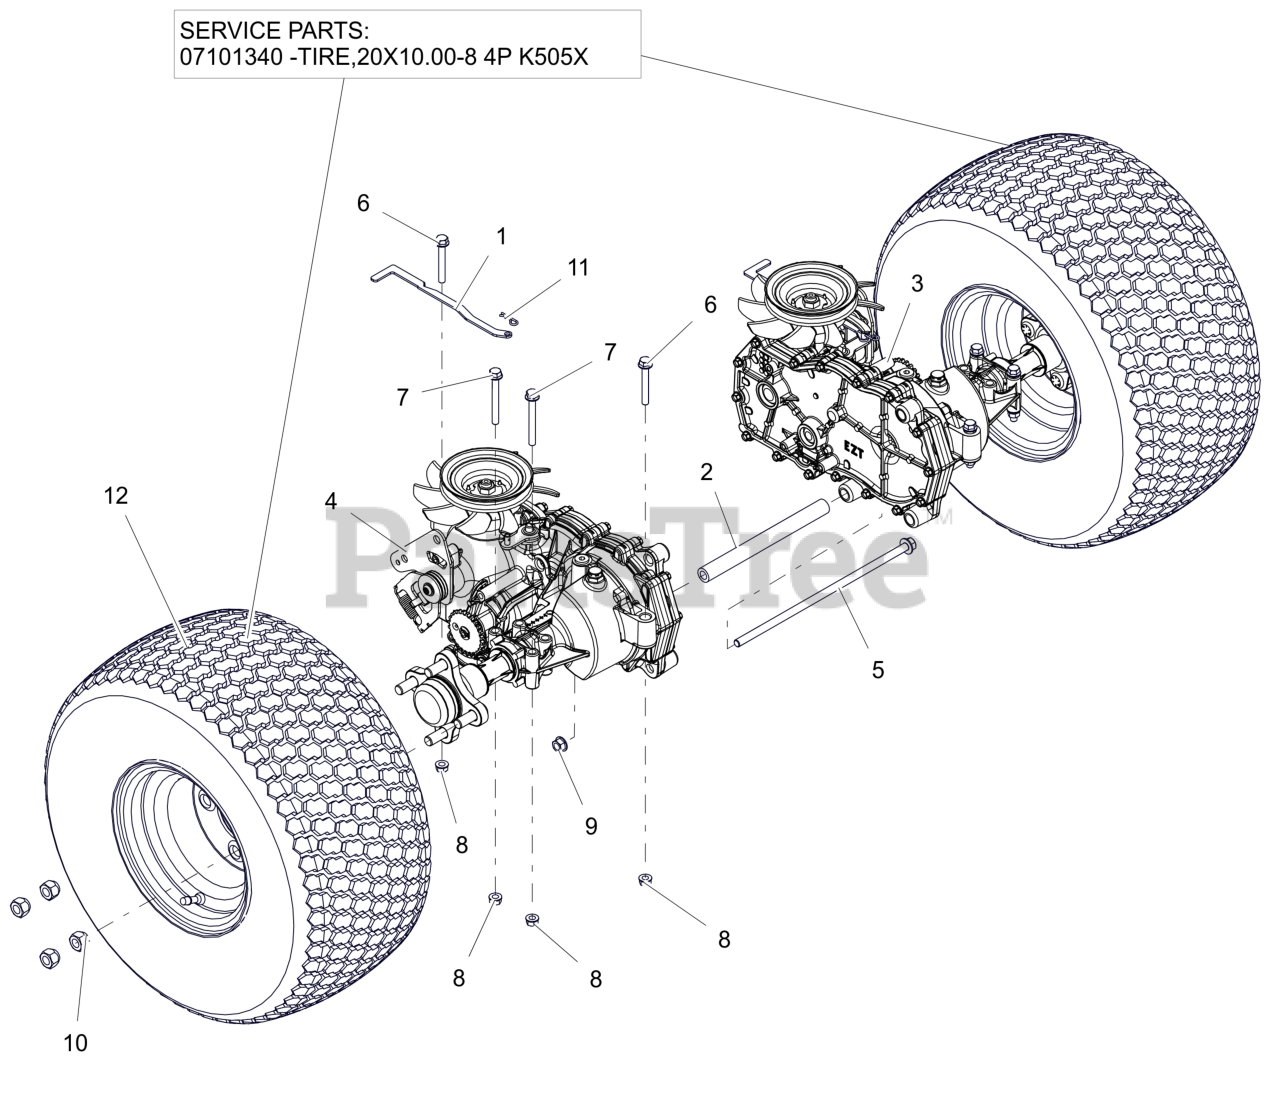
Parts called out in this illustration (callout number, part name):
1	BRKT, DUMP VALVE
2	TUBE, TRANSAXLE BRACE 8.18LG
3	TRANSAXLE
4	TRANSAXLE
5	BLT,HEX-FLG .38-16X11.5 G5 ZCC
6	BLT,HEX-FLG .31-18X2.25 G5 ZCC
7	BLT,HEX-FLG .31-18X2.75 G5 ZCC
8	NUT,LK-CTR-FLG .31-18 GF ZCC
9	NUT-LK-CTR-FLG .375-16 GF ZCC
10	NUT, WHEEL .50-20 ZCC
11	PIN, HAIR #213 .08X1.19 ZCC
12	ASM- TIRE/WHEEL 20X10-8
12	LAWN TIRE REAR, 4 PLY kK505 20/10.00-8
